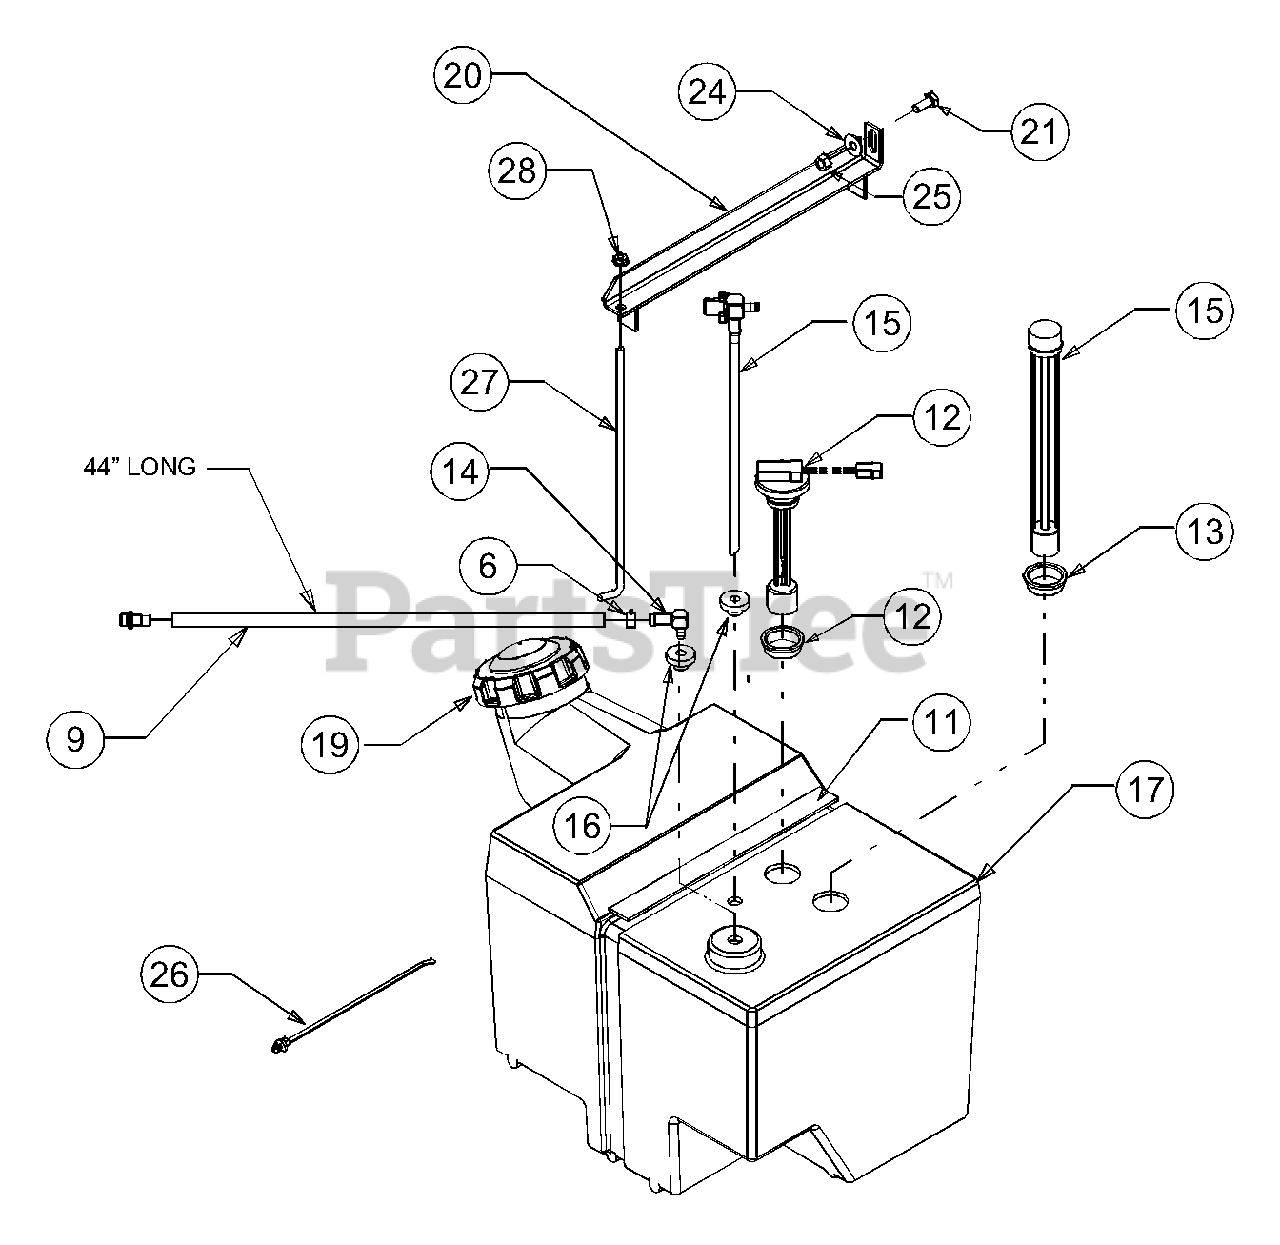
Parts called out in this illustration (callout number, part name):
6	Clamp, Hose
9	Hose, Fuel Line
11	Gasket, Fuel Tank, 11.5
12	Switch, Fuel Level Gauge
13	Grommet, 1.58 OD x 1.21 ID x .5
14	Fitting, Elbow, .190 ID
15	Valve, Fuel Tank
16	Grommet, 1.06 OD x .362
17	Tank, Fuel
19	Cap, Fuel, 3.5
20	Bracket Assembly, Fuel Tank
21	Hex Screw, 5/16-18 x .75
24	Washer, .349 x .879 x .063
25	Sems Nut, 5/16-18
26	Cable Tie, Tree Mount
27	Hold-down Rod, Fuel Tank
28	Nut, Flange Lock, 1/4-20
